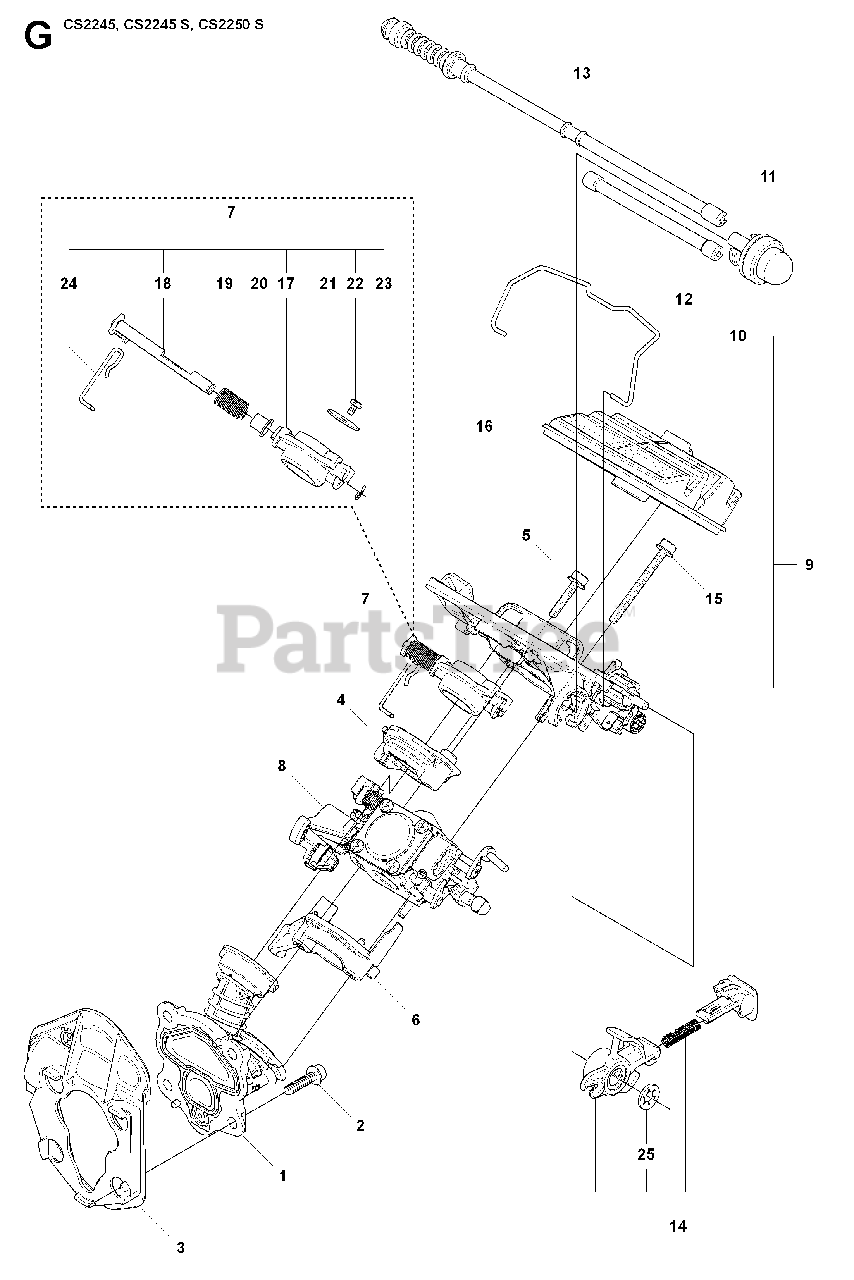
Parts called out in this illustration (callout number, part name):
1	INLET PIPE ASSY
3	INTERMEDIATE WALL
8	CARBURETOR
9	%FILTER HOLDER ASSY
11	AIR PURGE BUBBLE
13	RP RETURN HOSE
16	AIR FILTER - NYLON (80)
16	AIR FILTER - NYLON (44)
16	AIR FILTER - FELT
18	SHAFT ASSY
25	LOCK WASHER
